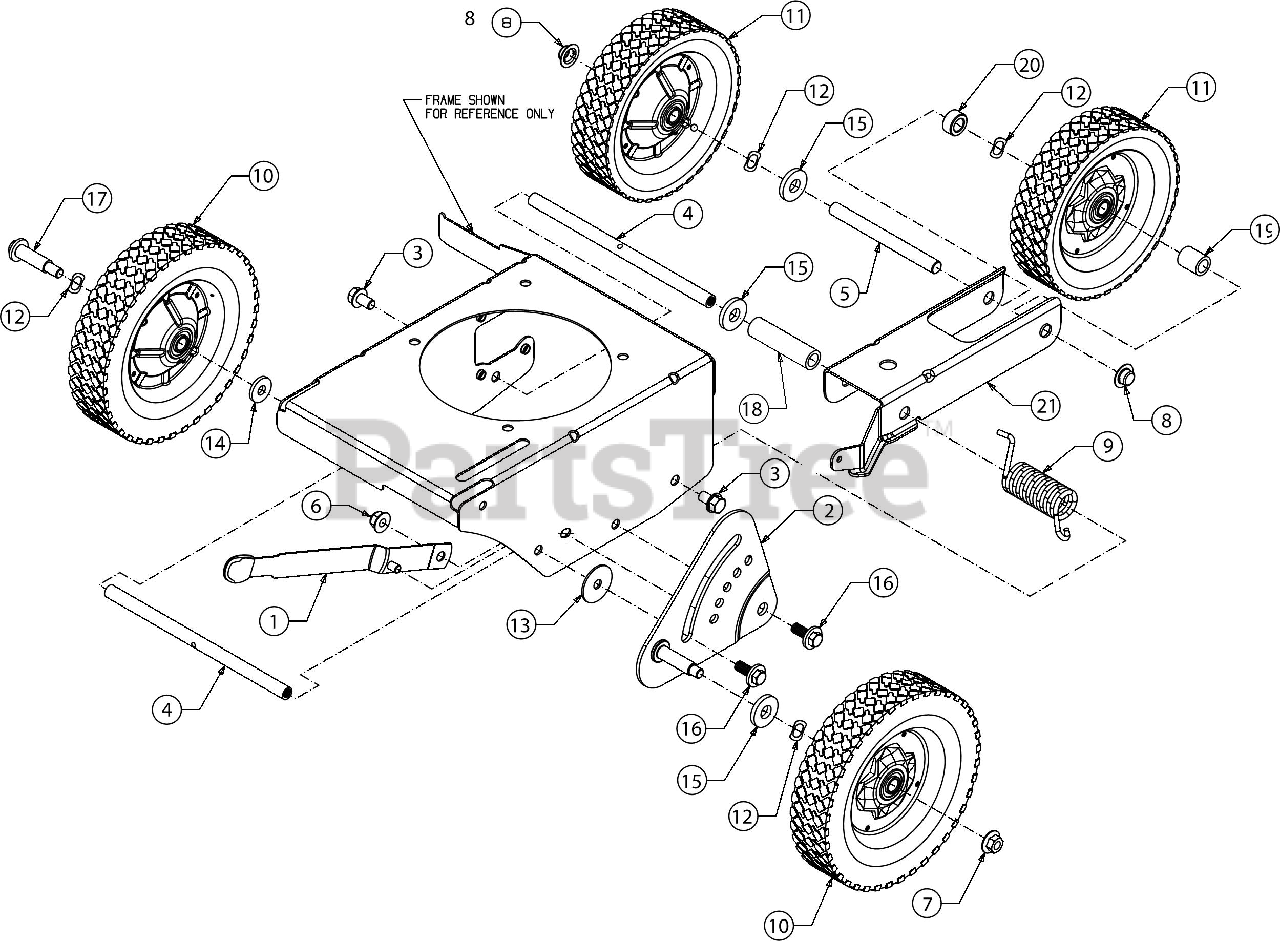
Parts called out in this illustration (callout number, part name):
1	WHEEL ADJUSTMENT LEVER ASSEMBLY
1	HEIGHT ADJUSTMENT KNOB
2	HEIGHT ADJUMENT ASSEMBLY
3	SCREW 3/8-16X.625 GR 5
4	SPACER .50 x 9.25
7	FLANGE LOCK NUT
9	TORSION SPRING
10	TIRE & WHEEL ASSEMBLY
10	BALL BEARING
11	COMPLETE WHEEL 7 x 1.75
12	WAVE WASHER
13	FLAT WASHER .390 ID x 1.50 OD x .075
14	FLAT WASHER .385 x 1.00 x .135
15	FLAT WASHER .531 x 1.25 x .181
17	SHOULDER SCREW .496X1.44 3/8-16
20	SPACER-.505 1D
21	WHEEL BRACKET
